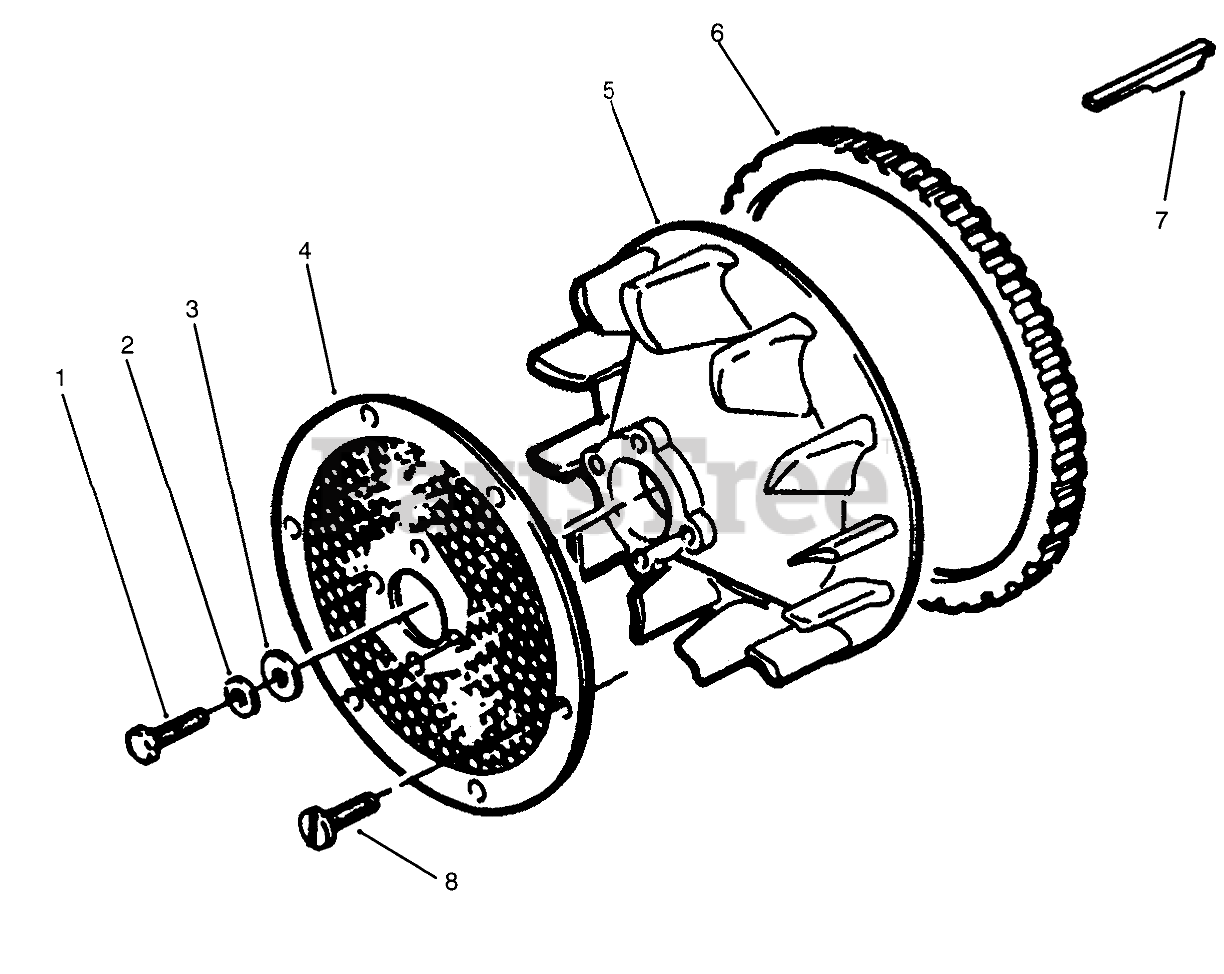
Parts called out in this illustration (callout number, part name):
1	SCREW
2	WASHER-FLAT
3	WASHER-FLAT
4	Screen
5	Flywheel (Incl. Ref. #6)
7	KEY-FLYWHEEL
8	LOCK SCREW
